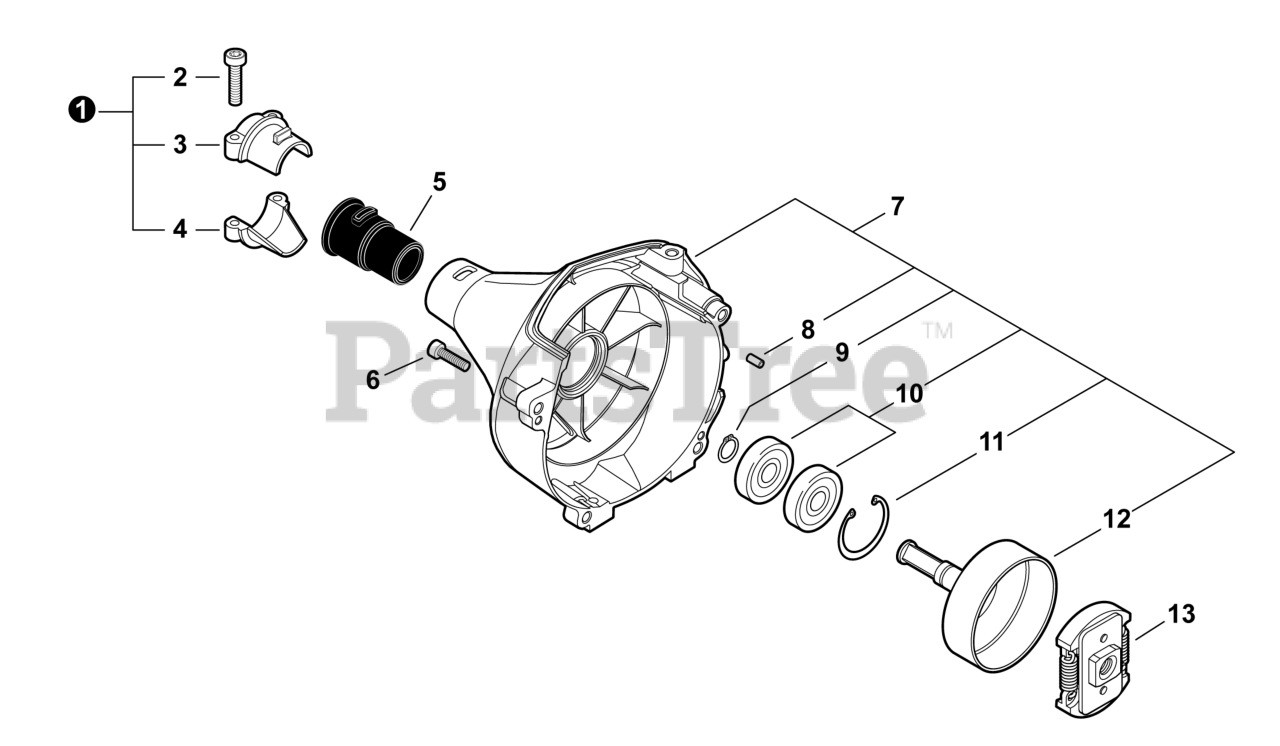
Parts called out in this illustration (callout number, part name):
1	HOLDER KIT
2	BOLT, TORX 5x20
3	HOLDER, MAIN PIPE - UPPER
4	HOLDER, MAIN PIPE - LOWER
5	CUSHION 25
6	BOLT, TORX 4x16
7	COVER ASSY, FAN
8	PIN, LOCATING 4x8
9	RING, SNAP 12
10	BEARING, BALL 6001
11	RING, SNAP 28
12	DRUM, CLUTCH
13	CLUTCH ASSY
